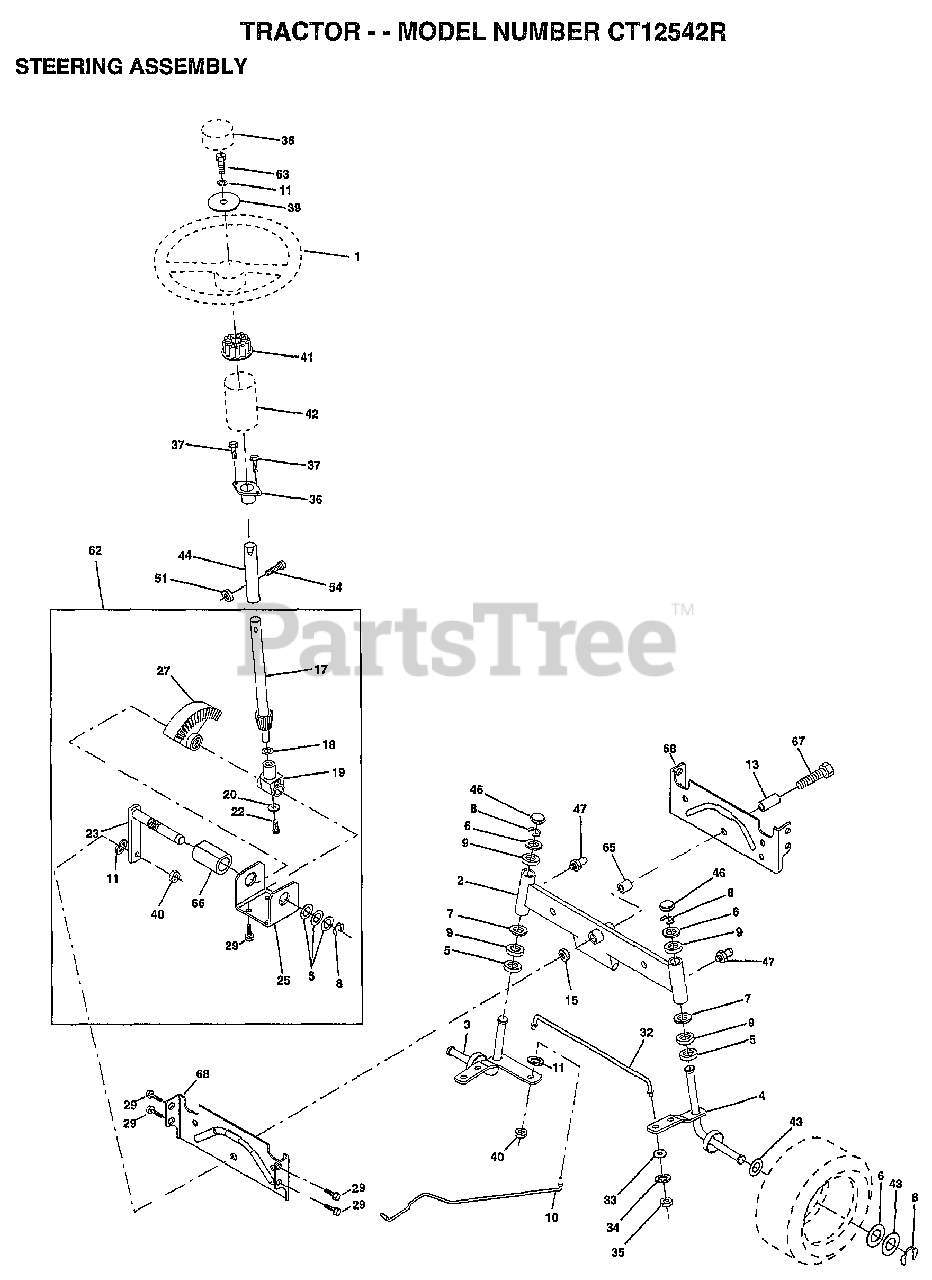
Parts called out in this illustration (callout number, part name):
1	WHEEL STR AYP BLK
2	AXLE ASM
3	SPINDLE.ASM.LH
4	"SPINDLE ASM,RH"
5	WASHER .T
6	WASHER
7	WASHER
8	RING
9	COL. SRTG. BEAR.
10	DRAGLINK-STAMPED
11	LOCKWASHER
13	BEARING AXLE
15	"NUT-LOC,FLANGE LT"
17	SHAFT ASM STEERIN
18	THRUST WASHER
19	SUPPORT.SHAFT
22	SCREW HEX SOC1/4-
25	BRKT-STEERING
27	GEAR SECTOR
29	SCREW
32	ROD.TIE.19.75
33	WASHER M
34	LOCKWASHER
35	NUT.LOCK.5/16-24
36	BUSHING.STEERING
37	"SCREW-TT,10-32 FL"
38	CAP STEER AYP
39	WASHER T
40	GRIPCO NUT
41	ADAPTER LT
42	BOOT.STEER.PL
44	EXT SHAFT STEERIN
46	CAP
47	ZERK M
51	NUT
54	BOLT
62	KIT STEERING ASM
63	BOLT
65	SPACER AXLE
66	"BEARING-ARM,PITMA"
67	BOLT
68	BRACE AXLE
